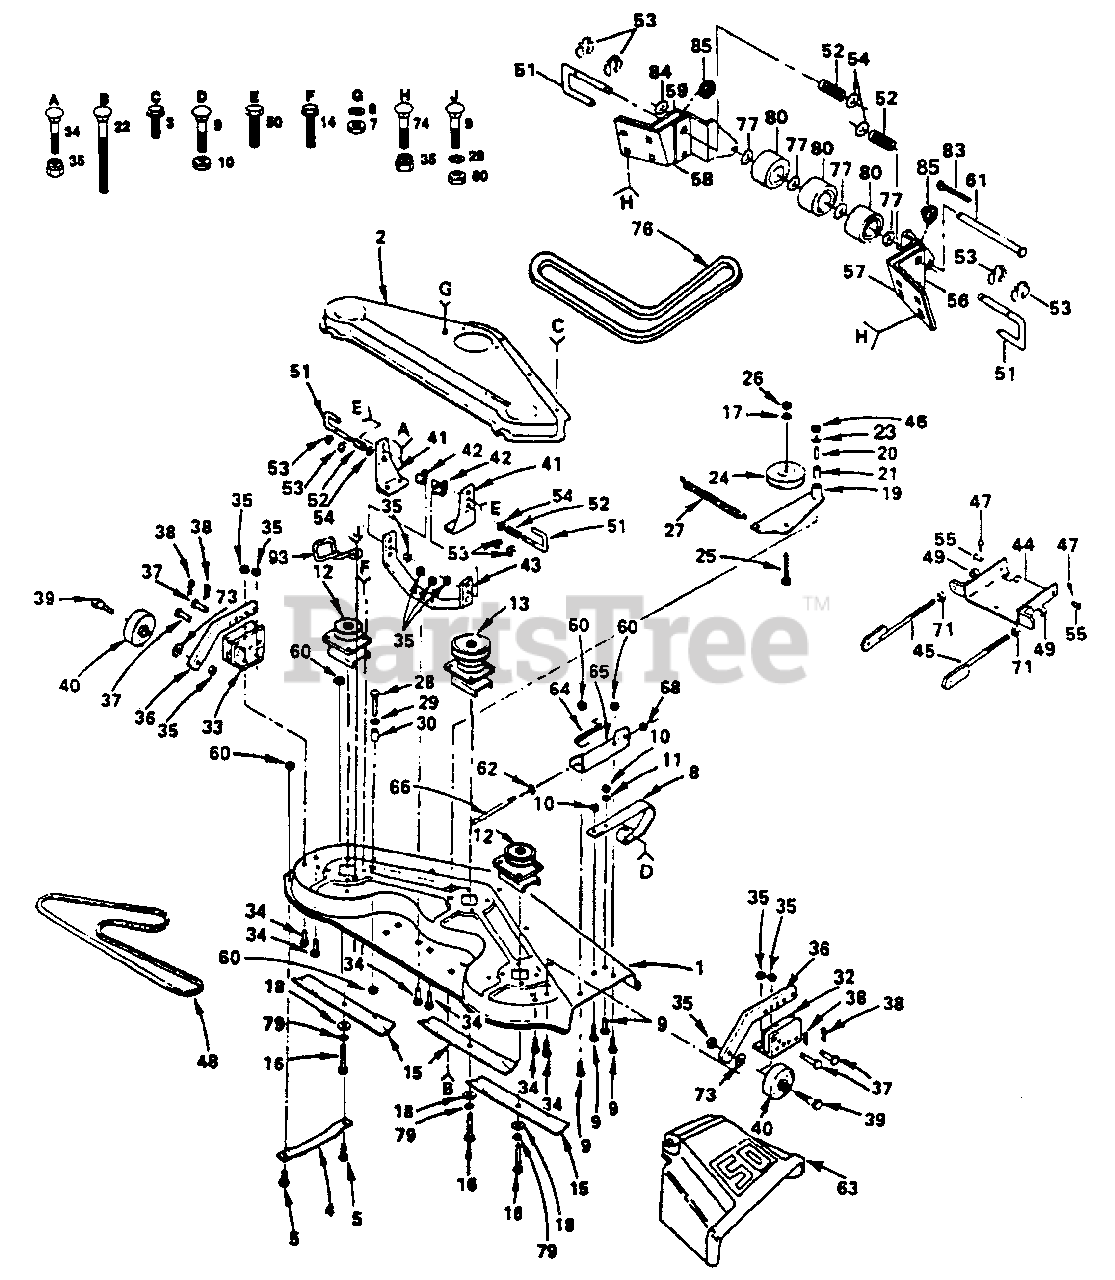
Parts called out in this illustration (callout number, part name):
1	Housing, Mower
2	Cover, Drive, Deck
3	Screw, Hex Washer Thr. Roll 5/16 18 x 1/2
4	Runner, L.H.
5	Bolt, Carriage 5/16-18 x 5/8
6	Washer, Lock 5/16
7	Nut, Hex 5/16-18
8	Runner
9	Bolt, Carr. 5/16-18 x 3/4
10	Locknut 5/16-18
11	Washer 11/32 x 11/16 x 16 Gauge
12	Mandrel, Secondary
13	Mandrel, Primary
14	Screw, Hex Washer Thrd. Roll 3/8 16 x 3/4
16	Bolt, Hex 3/8-24 x 1-1/2 Grade 5
17	Washer, Lock 3/8
18	Washer 13/32 x 1-1/4 x 12 Gauge
19	Arm Assembly, Idler
20	Liner, Bearing
21	Bearing
22	Bolt, Carriage 5/16-18 x 2-3/4
23	Washer 11/32 x 1-1/8 x 16 Gauge
24	Pulley, Idler
25	Bolt, Hex 3/8-16 x 1-1/2
26	Nut, Hex 3/8-16
28	Bolt, Hex 5/16-18 x 1-1/4 Grade 5
29	Washer 11/32 x 3/4 x 16 Gauge
30	Spacer, Split
32	Bracket, Ga. Wheel, R.H.
33	Bracket, Ga. Wheel, L.H.
34	Bolt, Carriage 3/8-16 x 3/4
35	Nut, Crownlock 3/8-16
36	Bar, Ga. Wheel
37	Pin, Clevis
38	Retainer, Spring
39	Bolt, Shoulder
40	Wheel, Gauge
41	Bracket, Suspension
43	Brace, Suspension
44	Plate Assembly, Mower Suspension
45	Bracket, Suspension
46	Nut, Hex 5/16-18
47	Clip, Hairpin
49	Nut, Crownlock 1/2-13
50	Bolt, Hex 3/8-16 x 1-3/8
51	Pin, Release
53	Ring, Klip
54	Washer 17/32 x 1 x 12 Gauge
55	Pin, Clevis
56	Bracket, Outer, R.H.
57	Bracket, Inner, R.H.
58	Bracket, Inner, L.H.
59	Bracket, Outer, L.H.
60	Locknut 5/16-18
61	Pin, Pivot
62	Washer 11/32 x 5/8 x 16 Gauge
63	Shield, Deflector
64	Spring, Deflector
65	Bracket, Deflector
66	Rod, Hinge
71	Nut, Hex 3/8 x 16
73	Washer 17/32 x 15/16 x 12 Gauge
74	Bolt, Carriage 3/8-16 x 1
77	Washer 15/32 x 1 x 10 Gauge
79	Washer, Lock 3/8
80	Roller, Nose
83	Pin, Cotter
84	Washer 15/32 x 1 x 16 Gauge
93	Keeper, Belt L.H.
